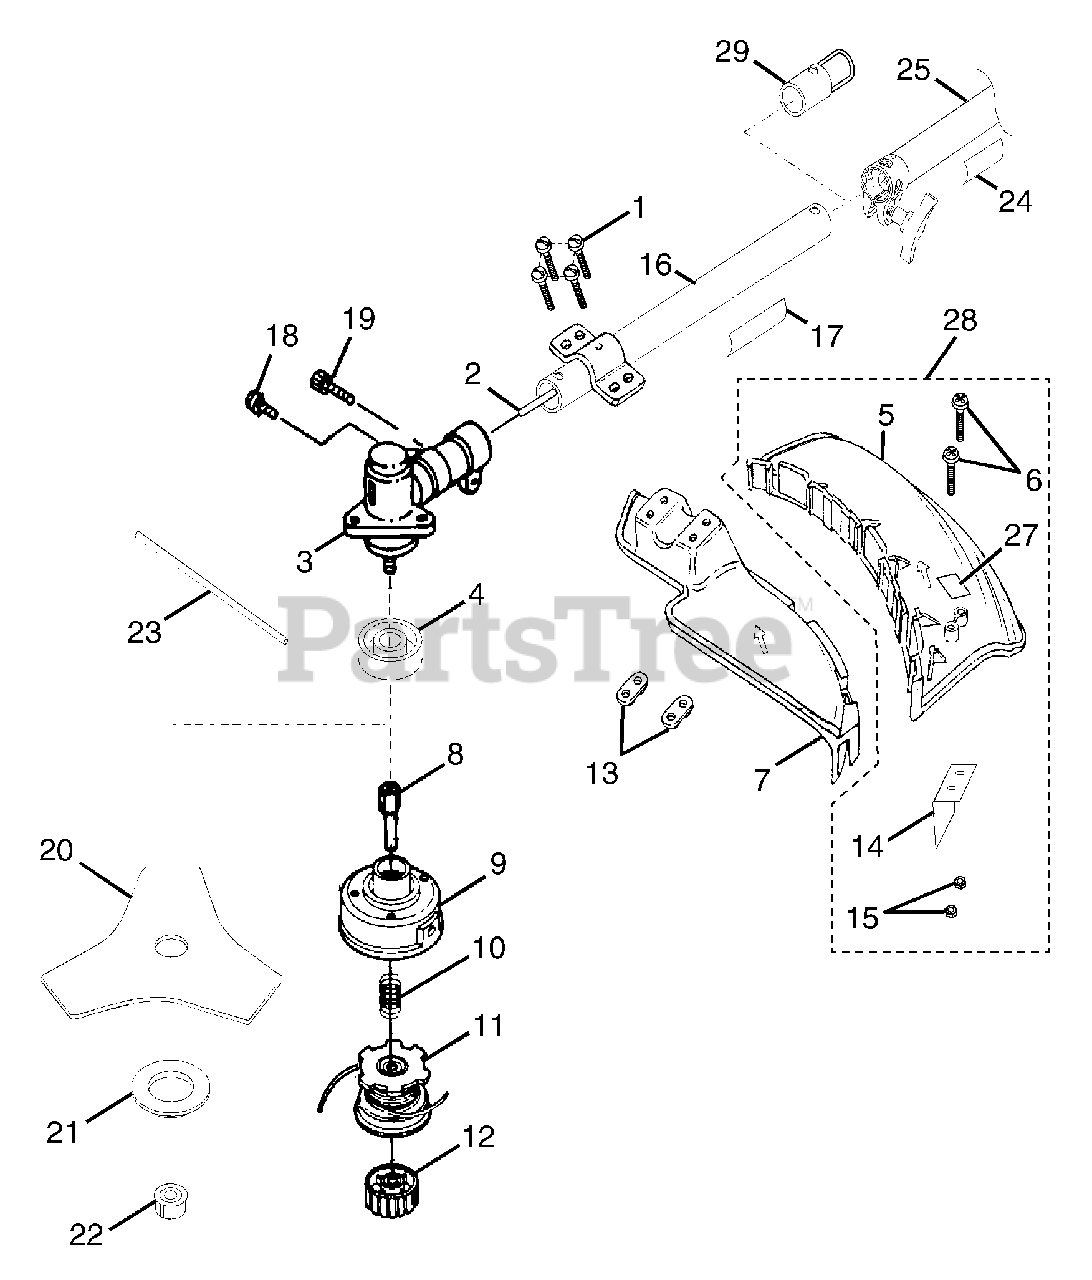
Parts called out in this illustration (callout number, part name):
2	FLEXIBLE SHAFT, LOWER
3	GEAR CASE ASSEMBLY
4	FLANGED WASHER
5	STRING SHIELD CCW
6	SCREW (10 - 24 x 7/8)
7	BLADE GUARD CCW
8	ADAPTER SHAFT/1986
9	HOUSING AND EYELETS
10	COMPRESSION SPRING
11	SPOOL AND STRING (.95)
12	SPOOL RETAINER (L/H THREAD)
13	MOUNTING PLATE
14	CUT OFF BLADE
15	HEX NUT
16	D.S. HOUSING
17	WARNING DECAL
18	SCREW (10-24 x .625 TAPTIT)
19	SCREW (1/4 - 20 x 1.25 TAP)
20	TRI-ARC BLADE
21	CUPPED WASHER
22	LOCK NUT
23	HOLDING PIN
24	WARNING DECAL
25	UPPER BOOM ASSEMBLY
27	WARNING DECAL
28	STRING SHIELD ASSEMBLY
29	END CAP STORAGE
